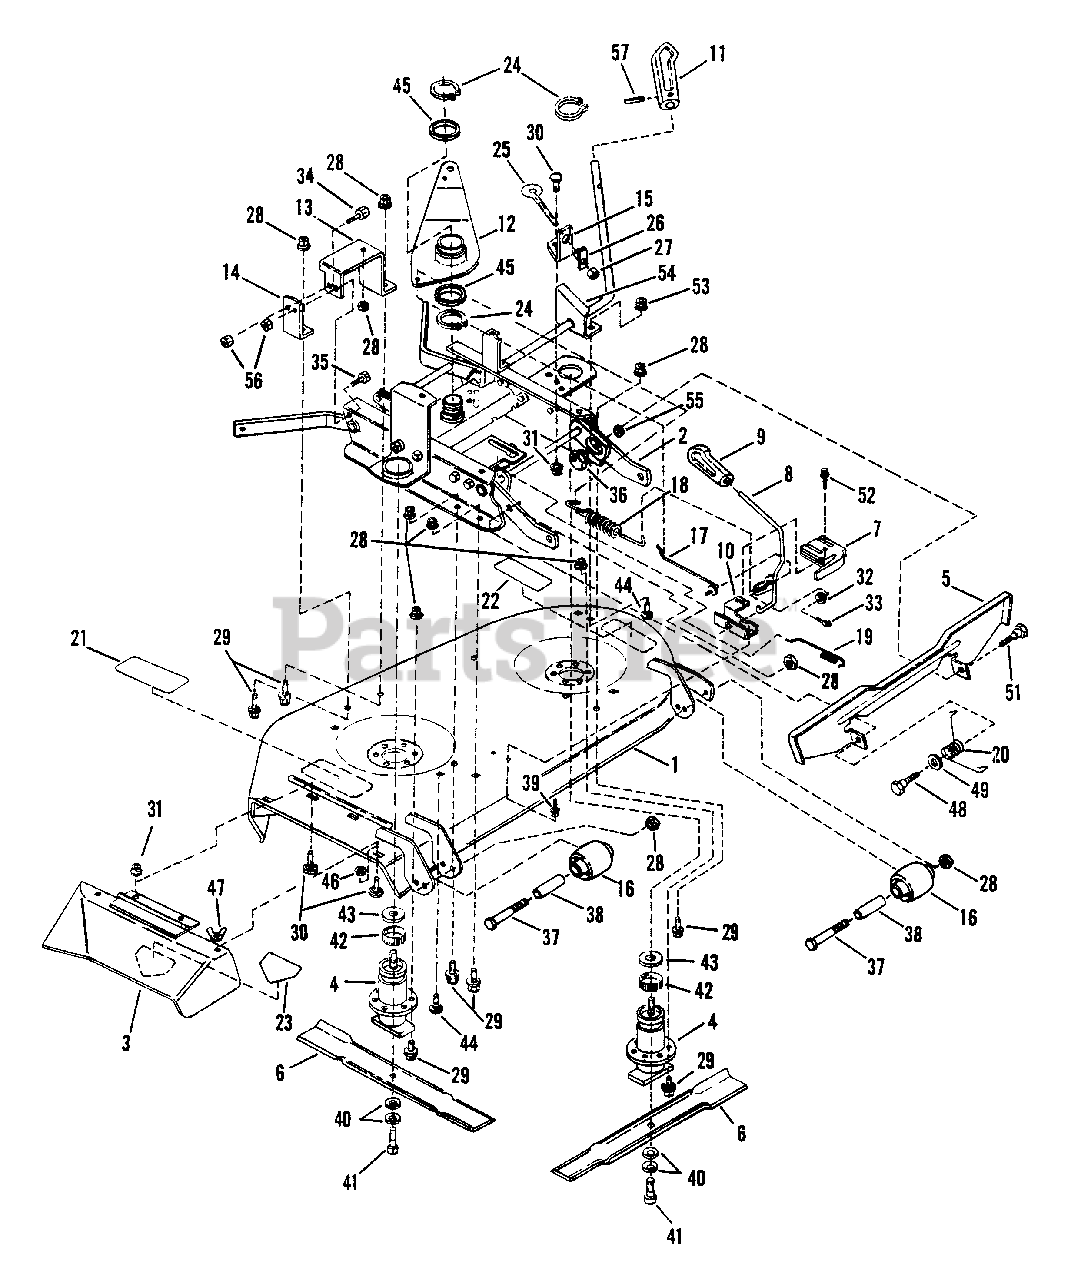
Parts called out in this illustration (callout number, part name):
1	ASSEMBLY, Deck
2	ASSEMBLY, Rail
3	ASSEMBLY, Side Chute
4	ASSEMBLY, Spindle
5	ASSEMBLY, Pedal
6	21" BLADE
7	SWITCH, Deck Interlock
8	LEVER, Blade Engagement
9	GRIP, Handle
10	MOUNT, Handle
11	GRIP, Height Adjustment Lever
12	ARM, Idler
13	SUPPORT, Idler
14	BRACKET
15	ANCHOR
16	ROLLER
17	ROD, Idler
18	SPRING, Belt
19	SPRING, Latch
20	SPRING, Pedal
21	DECAL, Caution
22	DECAL, Caution Rotating Blades
23	DECAL, Danger
24	RING, 2" External Retaining
25	BOLT, 1/4-20 Eye
26	T-NUT, 1/4-20
27	NUT, 1/4-20 Hex
28	NUT, 3/8-24 Hex Head
29	SCREW, 3/8-24 x 3/4" Hex Head Cap
30	BOLT, 5/16-18 x 3/4" Carriage
31	NUT, 5/16-18 Hex Flange Lock
32	WASHER, 1/4 Flat
33	PIN, 3/32 x 3/4" Cotter
34	SCREW, 3/8-16 x 3/4" Hex Head Cap
35	SCREW, 3/8-16 x 1" Hex Head Cap
36	ECCENTRIC, Leveling
37	SCREW, 3/8-24 x 3-3/4" Hex Head Cap
38	SPACER
39	SCREW, 1/4-20 x 5/8" Self-Tapping
40	WASHER, Cone
41	SCREW, 3/8-24 x 1" Hex Head Cap
42	RING, Tolerance
44	BOLT, 3/8-16 x 3/4" Carriage
45	WASHER, 2" I.D. Nylon
46	RETAINER, 5/16 Bolt
47	NUT, 5/16-18 Wing
48	BOLT, 3/8-24 x 9/16" Shoulder
49	WASHER, 1/2 Flat
51	BOLT, 3/8-24 x 3/4" Shoulder
52	SCREW, #10-32 x 1" Self-Tapping
53	NUT, 3/8-16 Hex Lock
54	BRACKET, Height Indicator
55	WASHER, 3/8 Internal Tooth Lock
56	NUT, 3/8-16 Hex Lock
57	PIN, 3/16 x 3/4" Roll
